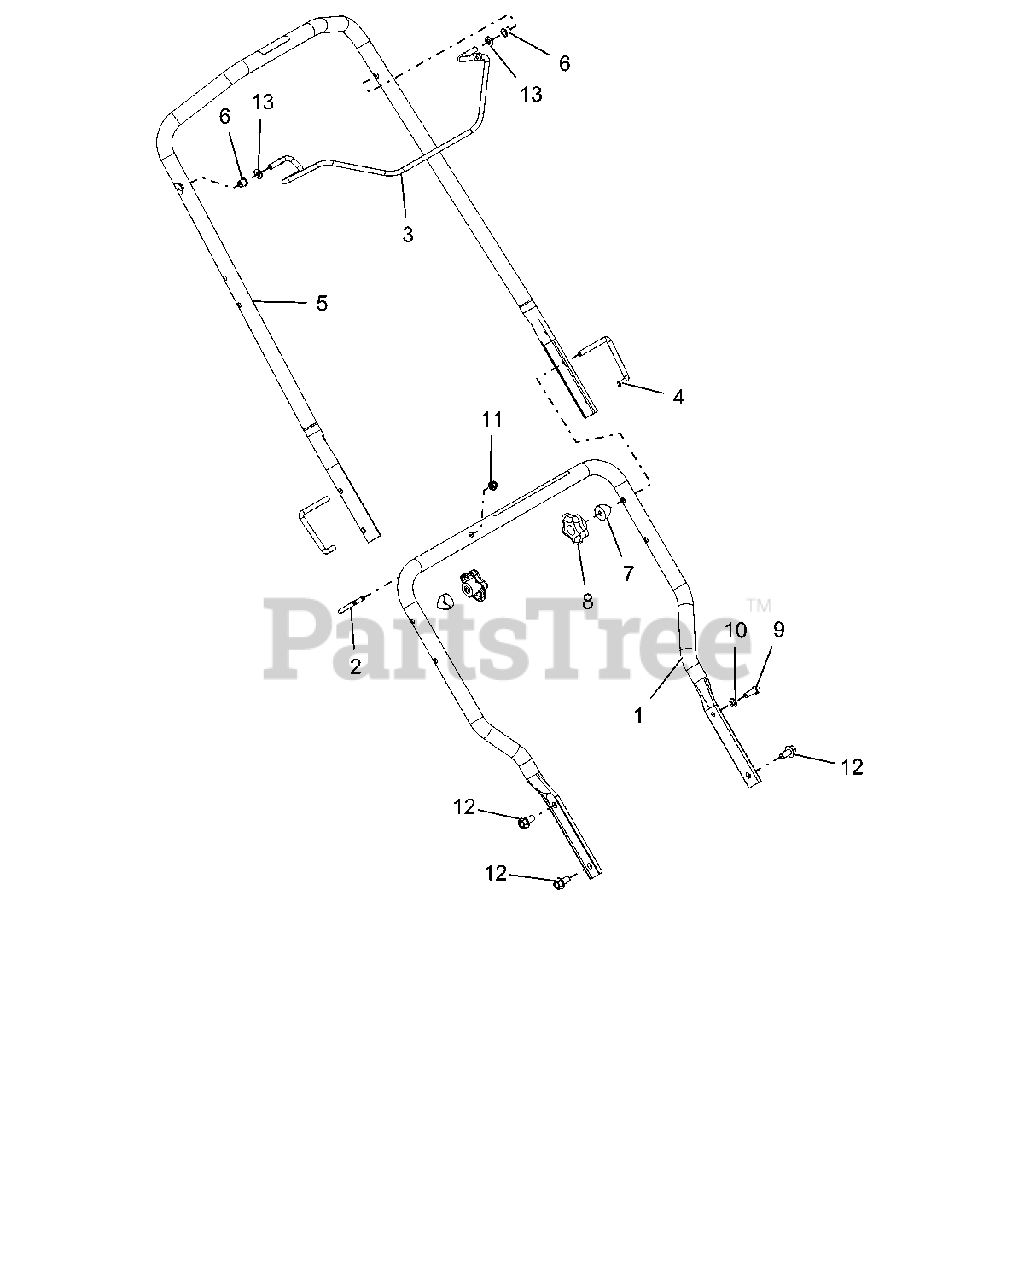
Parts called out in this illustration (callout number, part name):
1	HANDLEBAR, LOWER W/DECAL
2	GUIDE, PULL CORD
3	BAIL, AUGER
4	PIVOT, BOLT, HANDLEBAR
5	HANDLEBAR, UPPER W/DECAL
6	BSHG-FLG .325X.444X.440X.560
7	SPACER, HANDLEBAR
8	KNOB, STAR, 5/16-18UNC
9	BLT-HEX .31-24X.875 GR5YZ EP80
10	@WSHR-LK .31X.078 REG YWZC
11	@NUT-LK-TOP-FLG .25-20 YWZC
12	BLT-SERHFWH .38-16X.75 YWZC
13	@WSHR-FL-STL.344X.688X.065YWZC
